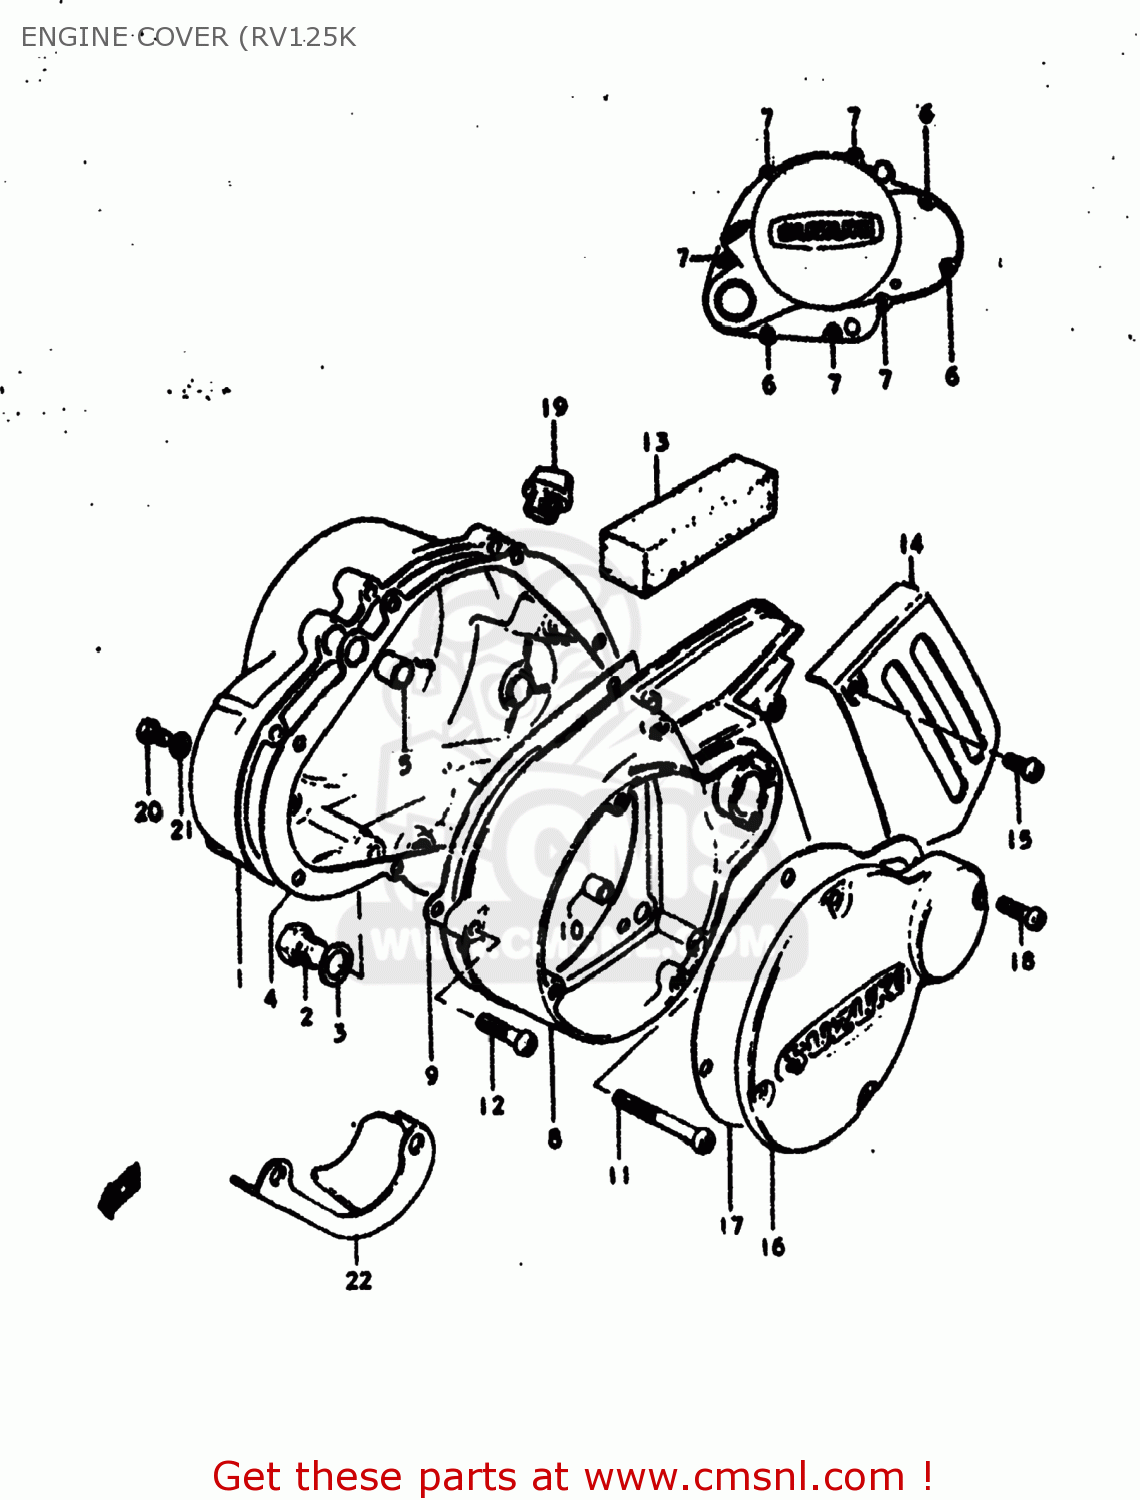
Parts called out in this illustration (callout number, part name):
1	CRANKCASE SET
2	PLUG
3	GASKET(14X19.2X2) (NAS)
4	GASKET,CLUTCH COVER (MCA)
5	PIN
6	SCREW
7	SCREW
8	COVER
9	GASKET,CLUTCH COVER (NAS)
10	PIN
11	SCREW
12	SCREW
13	SEAL,DUST
14	COVER,SPROCKET
15	SCREW
16	CAP,MAGNETO INSPECTION
17	GASKET,MAGNETO INSPECTION CAP (NAS)
18	SCREW
19	PLUG,OIL FILTER
20	SCREW(6X10)
21	GASKET(6.2X11X1) (NAS)
